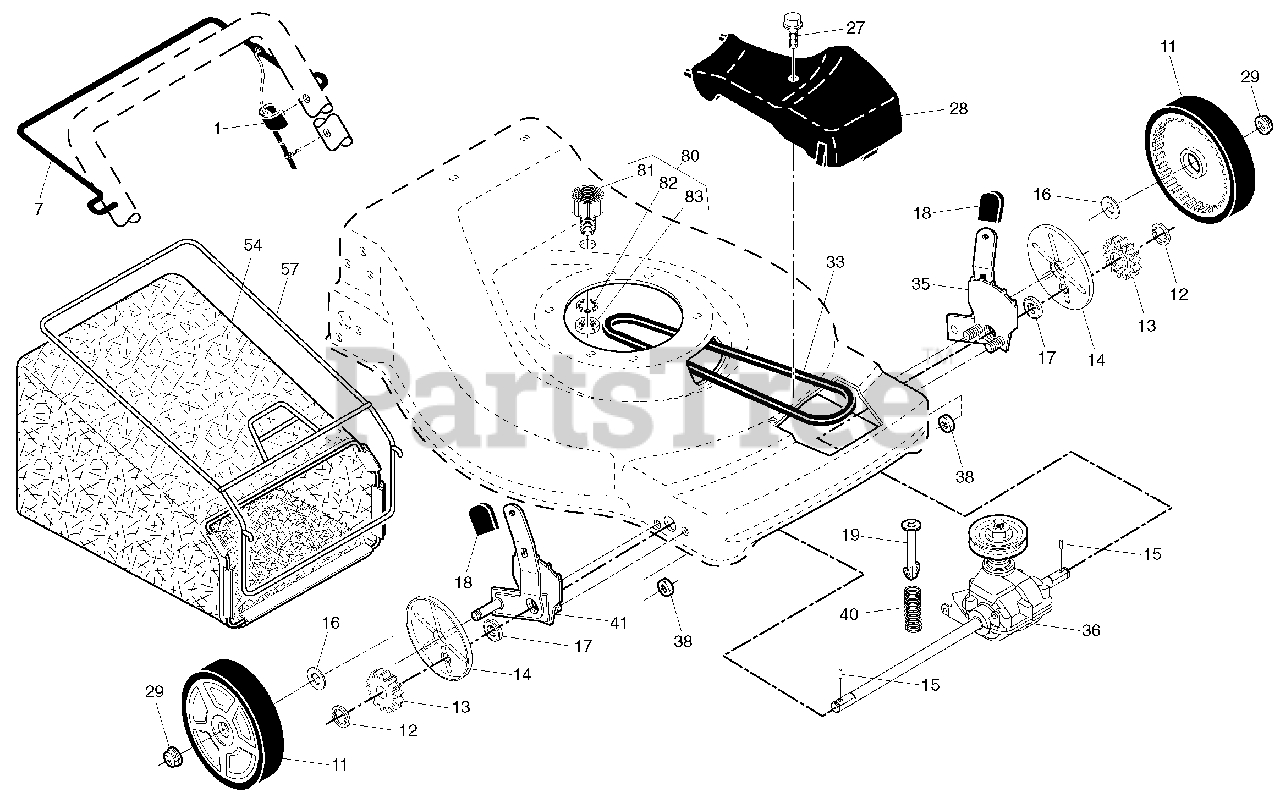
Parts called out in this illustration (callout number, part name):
1	Drive Control Cable
7	Bar, Drive Control
11	Wheel & Tire Assembly, Front
12	E-Ring
13	Pinion
14	Dust Cover
15	Pawl, Drive
16	Washer, Flat 3/8
17	Bearing, Wheel Adjuster Assembly
18	Selector Knob
19	Retainer, Spring
27	Pan Head Tapping Screw #10-24 x 2-3/4
28	Drive Cover
29	Locknut, Hex
35	Kit, Wheel Adjuster, LH
36	Gear Case Assembly, Complete
38	Locknut 1/4-20
40	Spring
41	Kit, Wheel Adjuster, RH
54	Grassbag Assembly
57	Frame, Grassbag
80	Water Washout Assembly
81	Fitting, Hose, Water Washout
82	Washer, Lock, Internal Tooth
83	Locknut, Hex, with O-Ring
